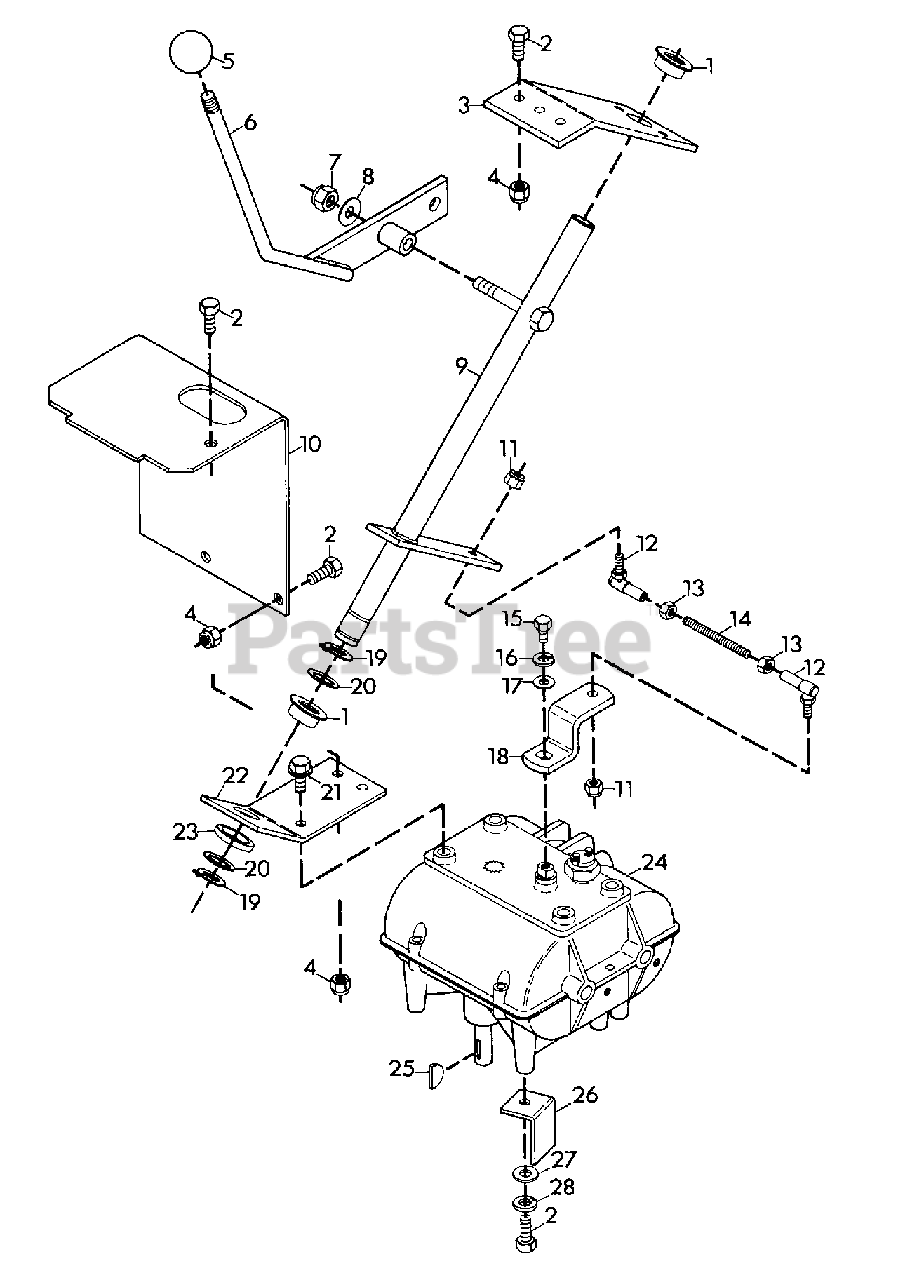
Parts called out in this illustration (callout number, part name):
1	BUSHING, NYLON .76X1X.6 FLANGE
2	BOLT, HEX 5/16-18X.75
3	PLATE, SHIFTER SUPPORT UPPER
4	NUT, HEX 5/16-18
5	KNOB, CONTROL
6	WELDMENT, SHIFT LEVER
7	NUT, LOCK 3/8-16
8	WASHER, FLAT .406X.812X.065
9	WELDMENT, SHIFTER SHAFT
10	GUARD, TRANSMISSION CHAIN
11	NUT, LOCK 1/4-28
12	BALL JOINT, DISCONNECTING
13	NUT, HEX 1/4-28
14	ROD, TRANS. SHIFTER
15	BOLT, HEX 1/4-28X.50
16	WASHER, LOCK 1/4
17	WASHER, FLAT .281X.625X.065
18	ARM, TRANS. SHIFT
19	RING, RETAINING
20	RACE, BEARING THRUST
21	BOLT, SELF-TAPPING 5/16-18X.62
22	PLATE, SHIFT SUPPORT LOWER
23	SPACER, SHIFTER SHAFT
24	TRANSMISSION, PRO LINE
25	KEY, WOODRUFF .187X.750 HARD
26	GUIDE, V-BELT
27	WASHER, FLAT .344X.688X.065
28	WASHER, LOCK 5/16 REG.
